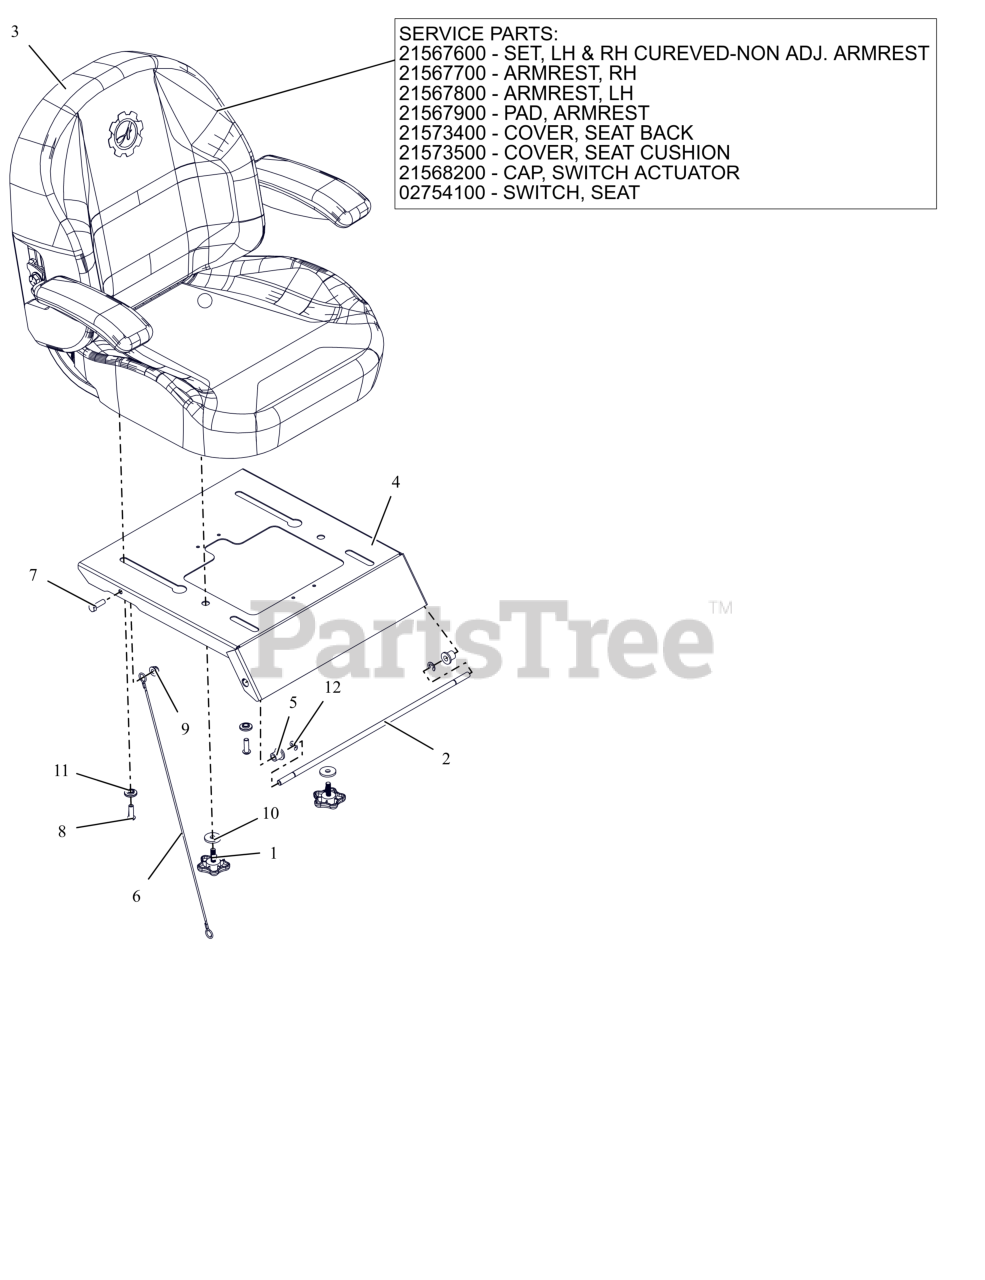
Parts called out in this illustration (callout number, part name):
1	KNOB, WING STUDDED
2	ROD, SEAT PIVOT
3	SEAT, 2020 IKON
3	SET,LH&RG CURVED-ARMREST
3	ARMREST-CURVED RH
3	ARMREST-CURVED LH
3	PAD, ARMREST (BLACK SELFSKIN)
3	COVER, SEAT BACK
3	COVER, SEAT CUSHION
3	CAP, SWITCH ACTUATOR
3	SWITCH- SNAP MTG N.O.
4	PLATE, SEAT (FASTENER SLIDE) (ORANGE)
5	BSHG-FLG .38X.580X.667X.750
6	LANYARD, SEAT CABLE .093X19.5
7	BLT,HEX .31-18X1.00 G5 ZCC
8	BLT,SHCS-BTN .31-18X1.00 ZCC
9	NUT,LK-NYL-FLG .31-18 G5ZC120
10	WSHR, FLT .340X1.125X.135 ZCC
11	BSHG, FLG .312X.499X.23X.88
12	RG-RTNG-EXT .375X.035 TYP E
